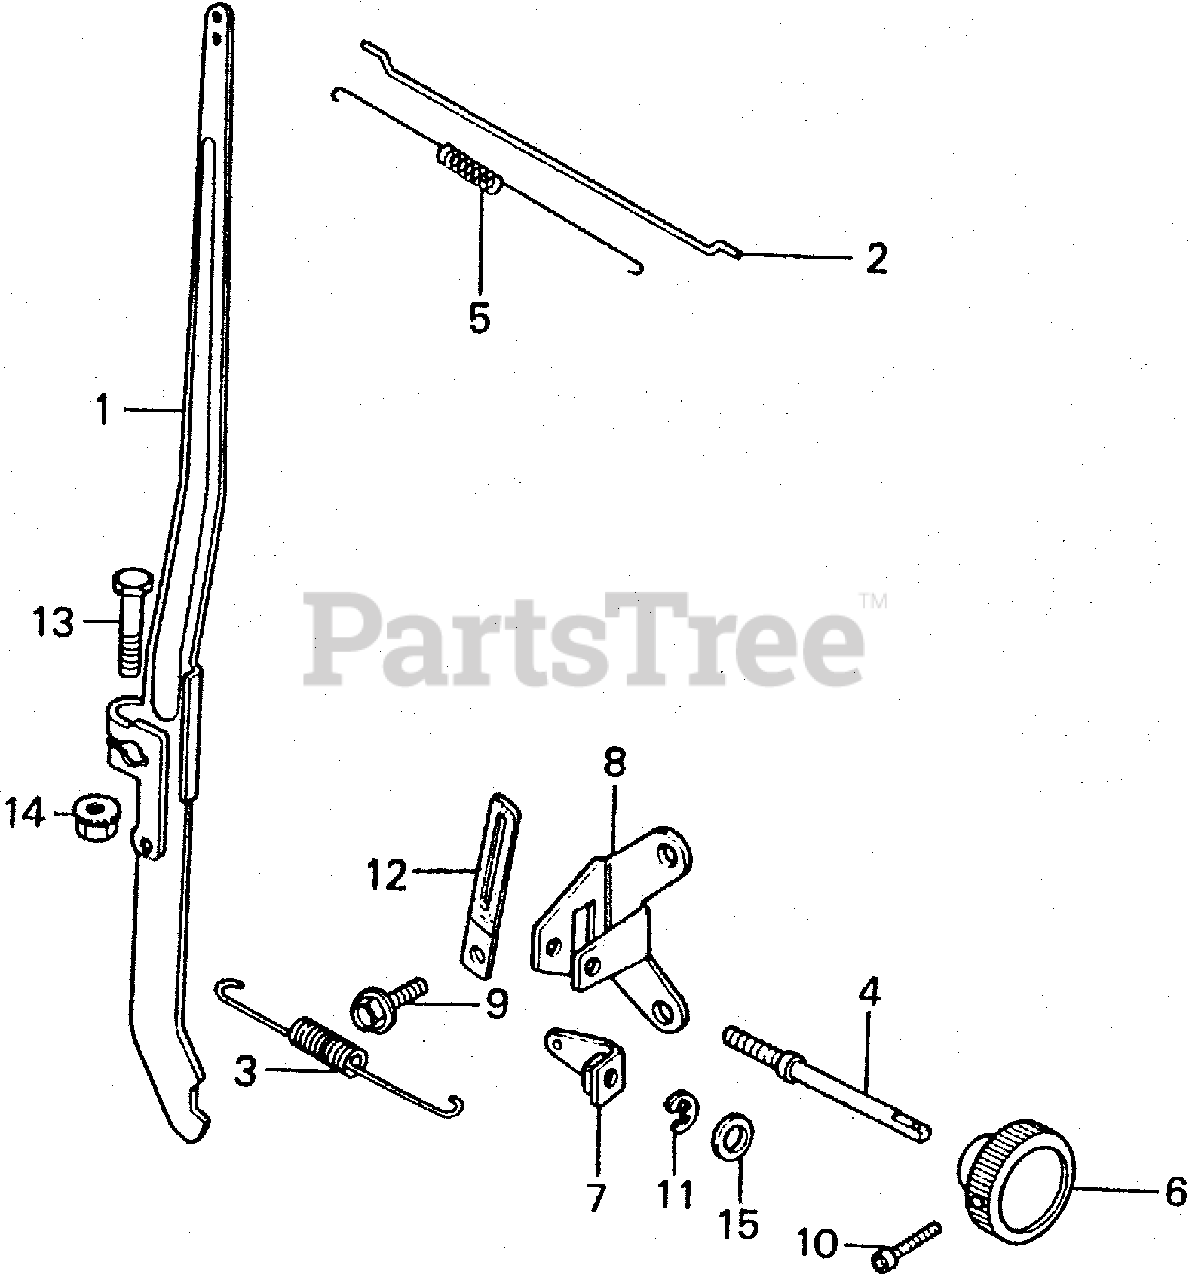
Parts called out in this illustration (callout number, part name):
1	ARM, GOVERNOR
2	ROD, GOVERNOR
3	SPRING, GOVERNOR
3	SPRING, GOVERNOR (NOT AVAILABLE)
4	SPRING, ADJUSTMENT
4	SPRING, ADJUSTMENT (NOT AVAILABLE)
5	SPRING, THROTTLE RETURN
6	KNOB, CONTROL
7	PLATE, CONTROL (NOT AVAILABLE)
8	BASE, CONTROL
8	BASE, CONTROL (NOT AVAILABLE)
9	BOLT, FLANGE (6X12) (CT200)
10	BOLT, KNOB (3MM) (NOT AVAILABLE)
12	CLIP, WIRE
13	BOLT, HEX. (6X25)
14	NUT, FLANGE (6MM)
15	WASHER, PLAIN (6MM)
